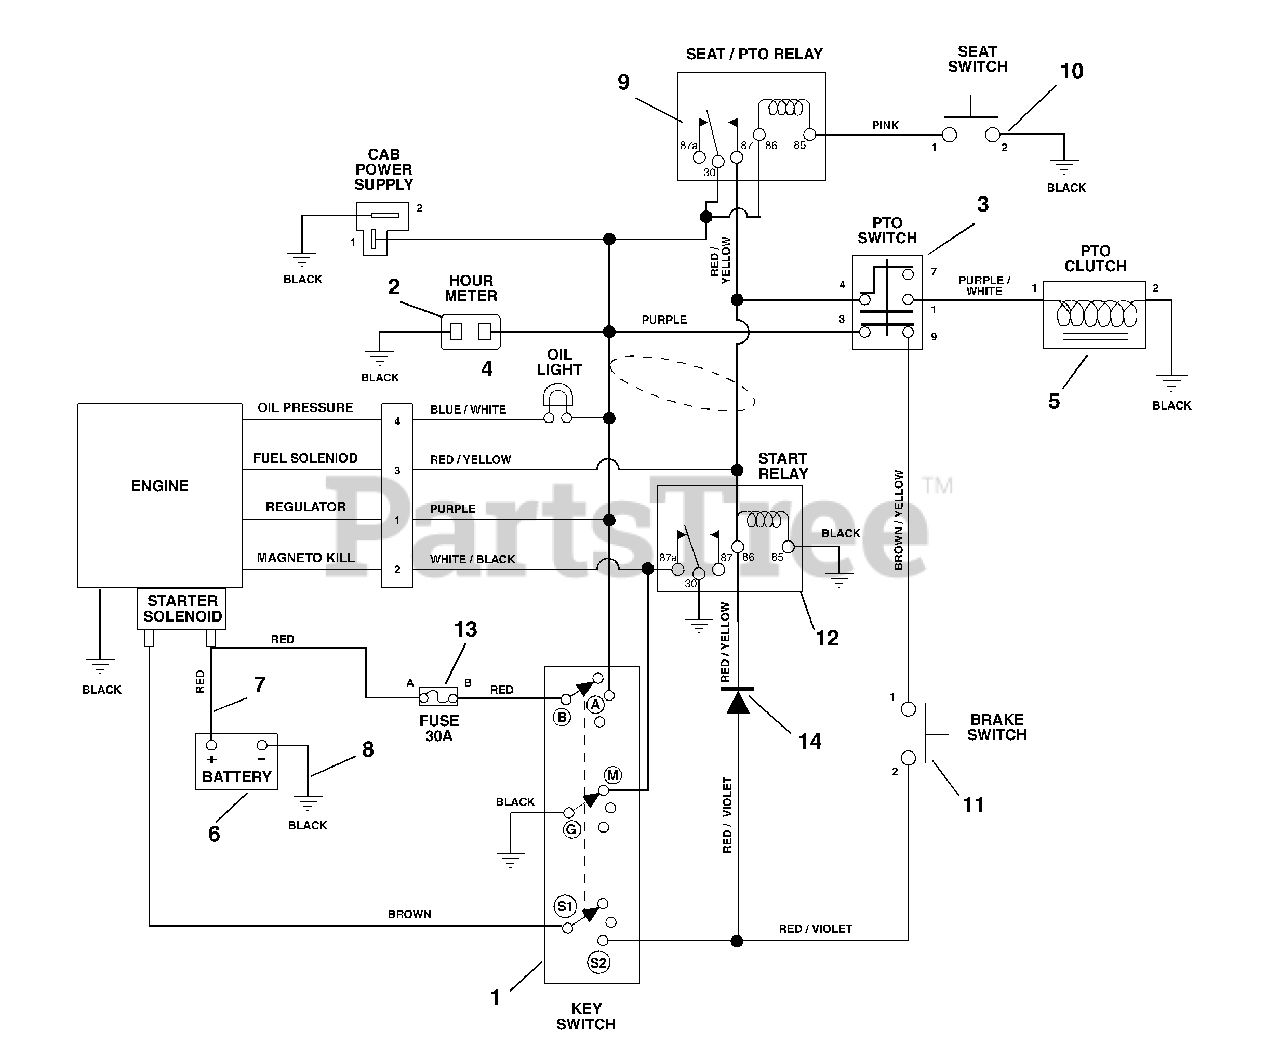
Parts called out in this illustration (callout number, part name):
1	Key Switch
2	Hour Meter
3	Switch-Clutch With Retainer Ring
4	Light-Indicator
5	Electric Clutch
6	Battery with Tube
7	Cable-Battery To Solenoid
8	Ground Cable
9	Relay
10	Seat Switch
11	Switch-Single Pole
12	Harness Kohler
13	Fuse, 30 Amp
14	Molded Diode Plug-Black 1-Amp
